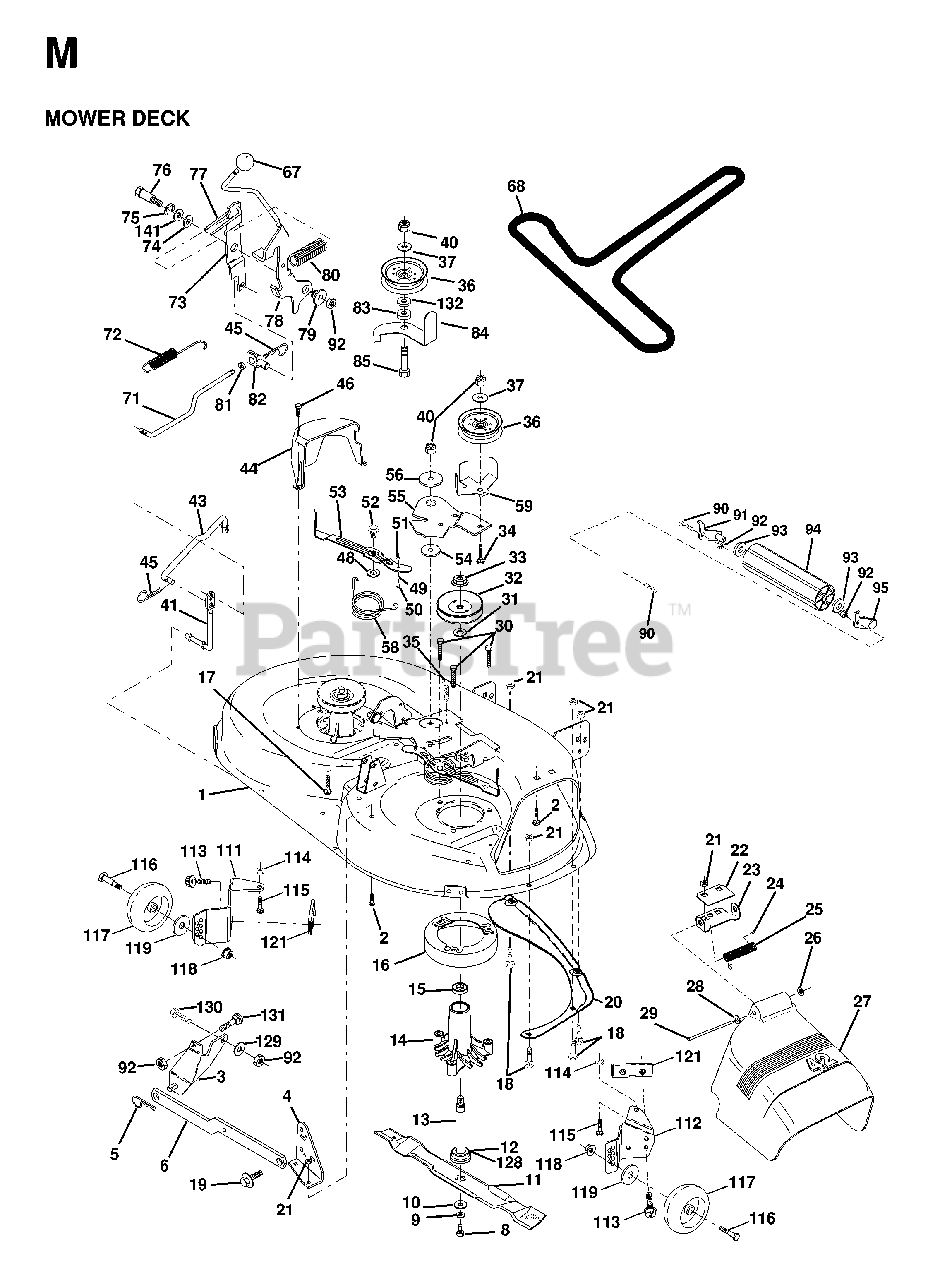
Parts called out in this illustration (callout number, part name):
1	DECK 42"
2	BOLT
3	BRKT ASM SWAY BAR
4	BRKT DECK SW BAR
5	RETAINER-SPRNG RB
6	REAR SUSP ARM
8	BLADE BOLT
9	LOCKWASHER
10	WASHER.BLADE
12	BEARING
13	SHAFT ASM VENT
14	HSG MANDREL
16	STRIPPER
17	BOLT
18	BOLT
19	BOLT SHD 5/16-18
20	BAFFLE
21	LOCKNUT
22	STIFFENER BRACKET
23	DEFLECTOR BRACKET
24	CAP-SLEEVE LT
25	SPRING TORSION
26	NUT PUSH M
27	SHIELD.DEFLECTOR.MOWER.42".BLK
28	WASHER
29	ROD.HINGE
30	SCREW THDROL ROLLING WASHER HD
31	WASHER
32	PULLEY/MANDREL
33	NUT
34	BOLT
35	FASTENER.XMAS.TREE
36	FLAT IDLER PULLEY
40	LOCKNUT
41	PIVOT ROD
43	CLUTCH ROD
44	GUARD MANDREL LH BLACK
45	RETAINER M
46	SCREW.1/4-20X5/8
49	ROLLER ASSY
50	BOLT
53	ARM ASM PAD BRAD
54	HARDENED WASHER
55	ARM IDLER 42" MOWER LT/YT
56	SPACER RETAINER
59	GUARD, BELT
67	KNOB.CONTROL.7/16
71	CLUTCH ROD
72	RETURN SPRING
73	ARM CLUTCH SECONDARY
75	RING CLIP
77	KEEPER SPRING
78	CLUTCH LEVER ASSY
79	BUSHING.FLANGE.E-RING.GROOVE
80	SPRING-CLUTCH
81	NUT
84	KEEPER.BELT.IDLER
85	BOLT
90	BOLT
91	BRACKET LH (A)
92	NUT
94	NOSE ROLLER
95	BRACKET RH (B)
111	BRACKET WHEEL GAUGE LH 42" DK
112	BRACKET WHEEL GAUGE RH 42" DK
113	SCREW
114	NUT
115	BOLT
118	LOCKNUT
119	WASHER
121	BRACKET.EXTRD.GWL
128	WASHER FELT
129	WASHER
130	BOLT
131	BOLT D
132	WASHER GT
